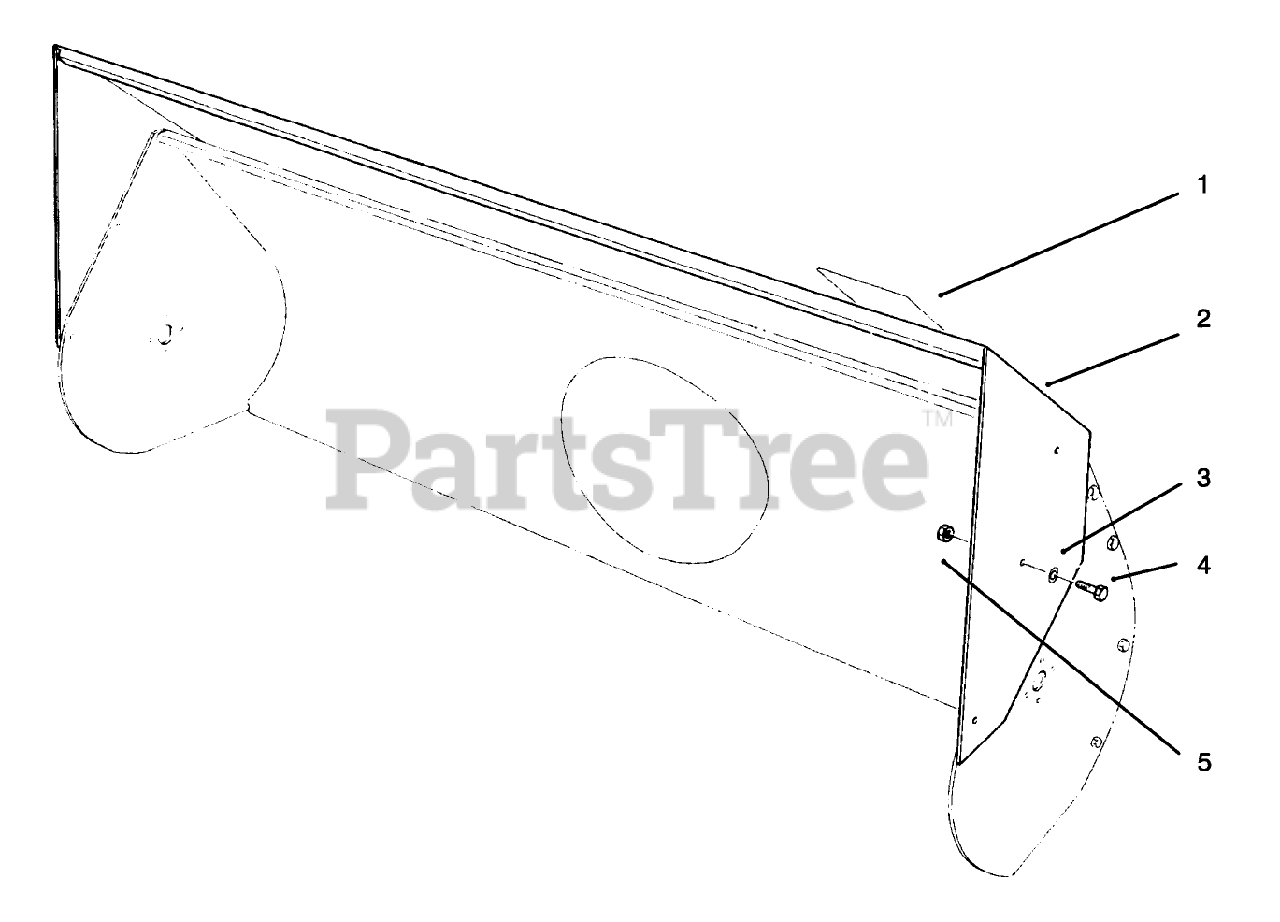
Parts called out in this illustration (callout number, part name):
1	Decal
2	Extension-Auger
3	WASHER-FLAT
4	SCREW-HH
5	NUT-LOCK, NI
